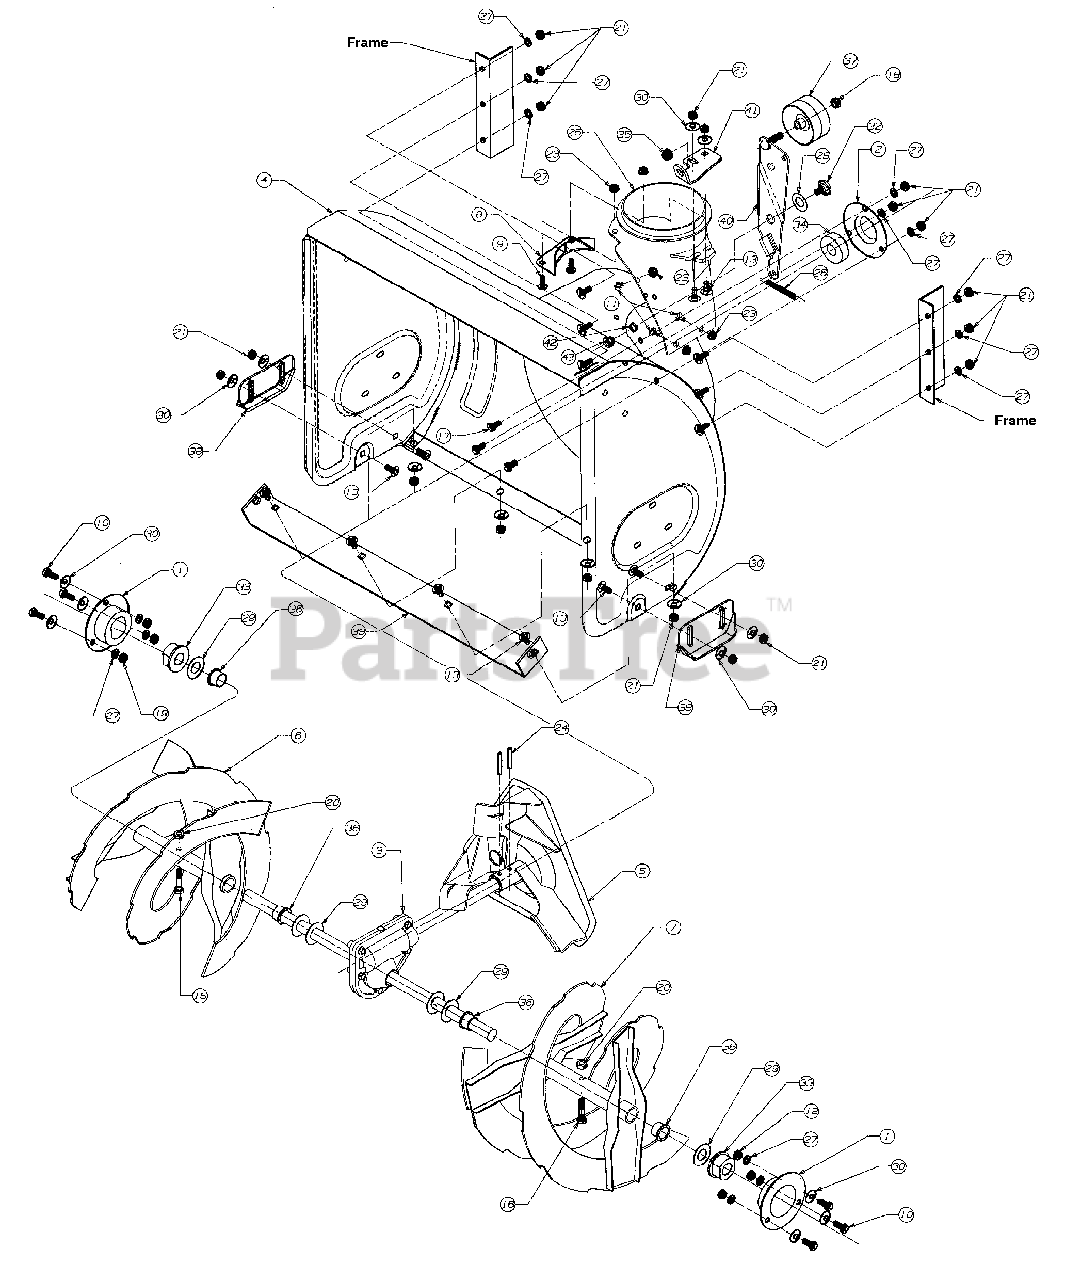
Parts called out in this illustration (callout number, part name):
2	Housing, Bearing
3	Gear Assembly (24")
3	Gear Assembly (26")
3	Gear Assembly (28")
3	Gear Assembly (30")
6	Spiral, 28" R.H.
6	Spiral, 30" R.H.
7	Spiral, 30" L.H.
9	Bolt, Carriage
10	Screw, Hex
11	Screw, Carriage
13	Screw, Carriage
16	Bolt, Shear
18	Hex Lock Nut
20	Nut, Hex Lock
21	Nut, Hex
23	Nut, Lock, Hex, Flanged
24	Spring Pin
25	Adapter, Chute
26	Spring
27	Lock Washer
28	Washer, Flat
29	Washer, Flat, .76 I.D. x 1.49 O.D. x .06
30	Washer, Bell
32	Screw, Shoulder
33	Bearing, Flange
34	Bearing, Ball
35	Bushing, Plastic
36	Bushing, Flange
37	Idler, Flat
39	30" Shave Plate
40	Arm, Auger Idler
42	Lock Washer
43	Hex Nut
